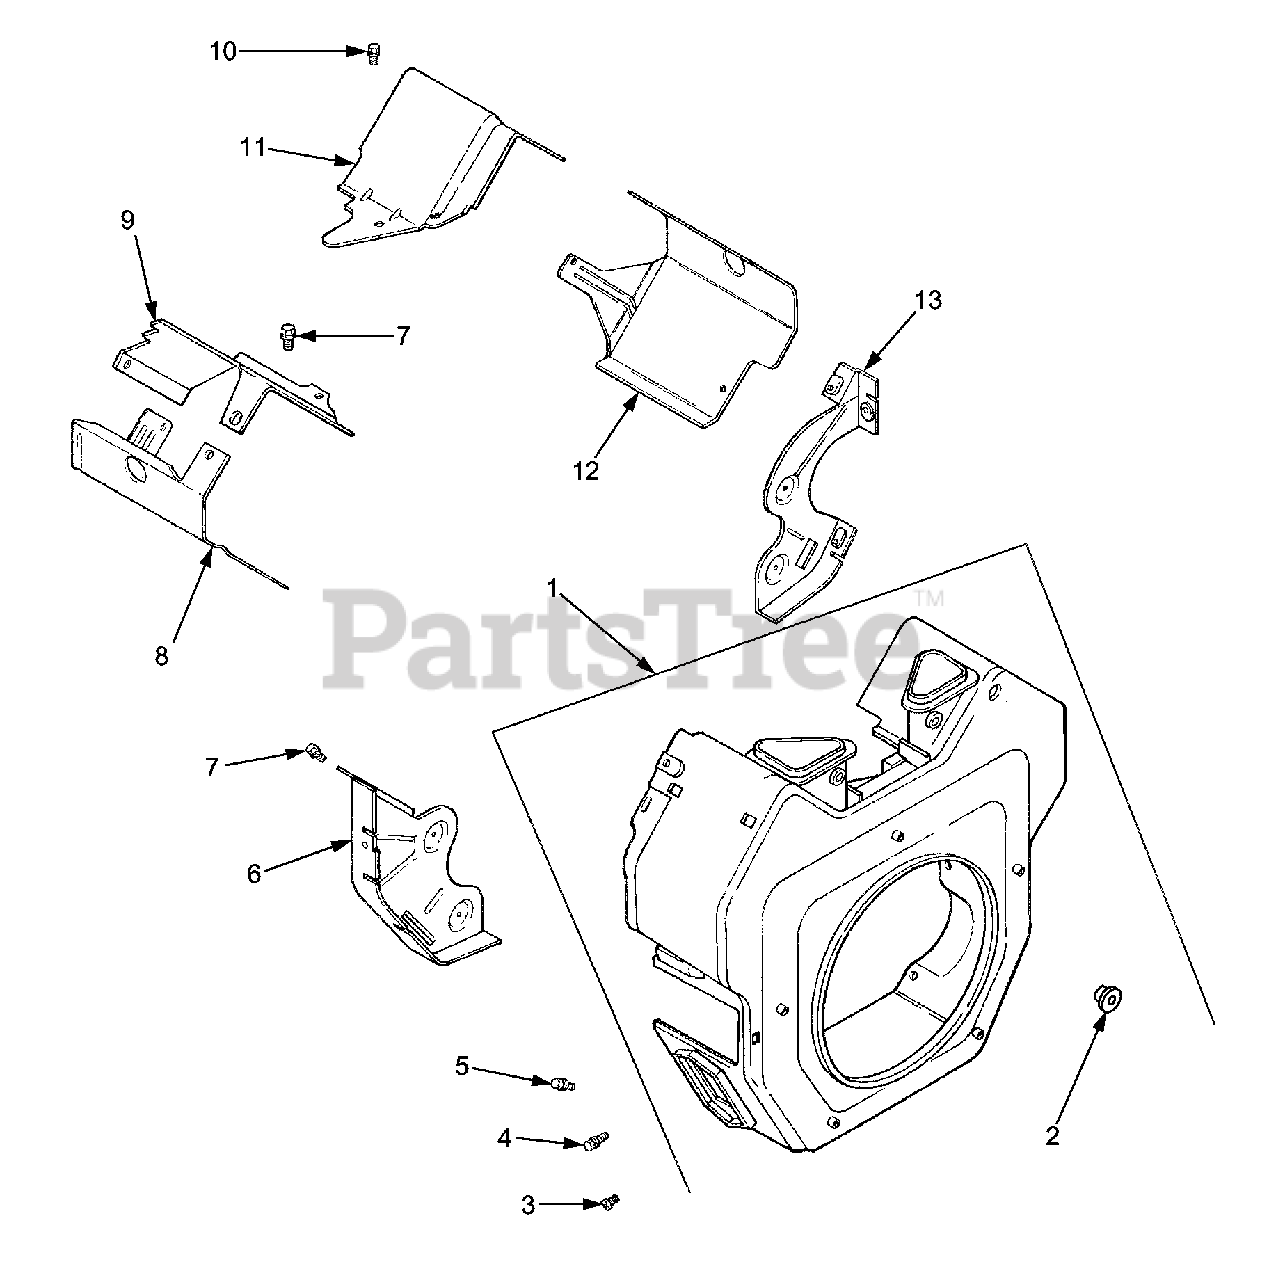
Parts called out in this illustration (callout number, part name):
1	Housing, Blower
3	Screw, Hex Flange M5 x 0.8 x 16
4	Screw, Hex Flange M5 x 0.8 x 16
5	Screw, Hex Flange M5 x 0.8 x 20
6	Plate, Backing #2 Side
7	Screw, Hex Flange M6 x 1.0 x 16
8	Baffle, Cyl. Barrel #2 Side
9	Baffle, Valley #2 Side
10	Screw, Hex Flange M5 x 0.8 x 10
11	Baffle, Valley #1 Side
12	Baffle, Cyl. Barrel #1 Side
13	Plate, Backing #1 Side
